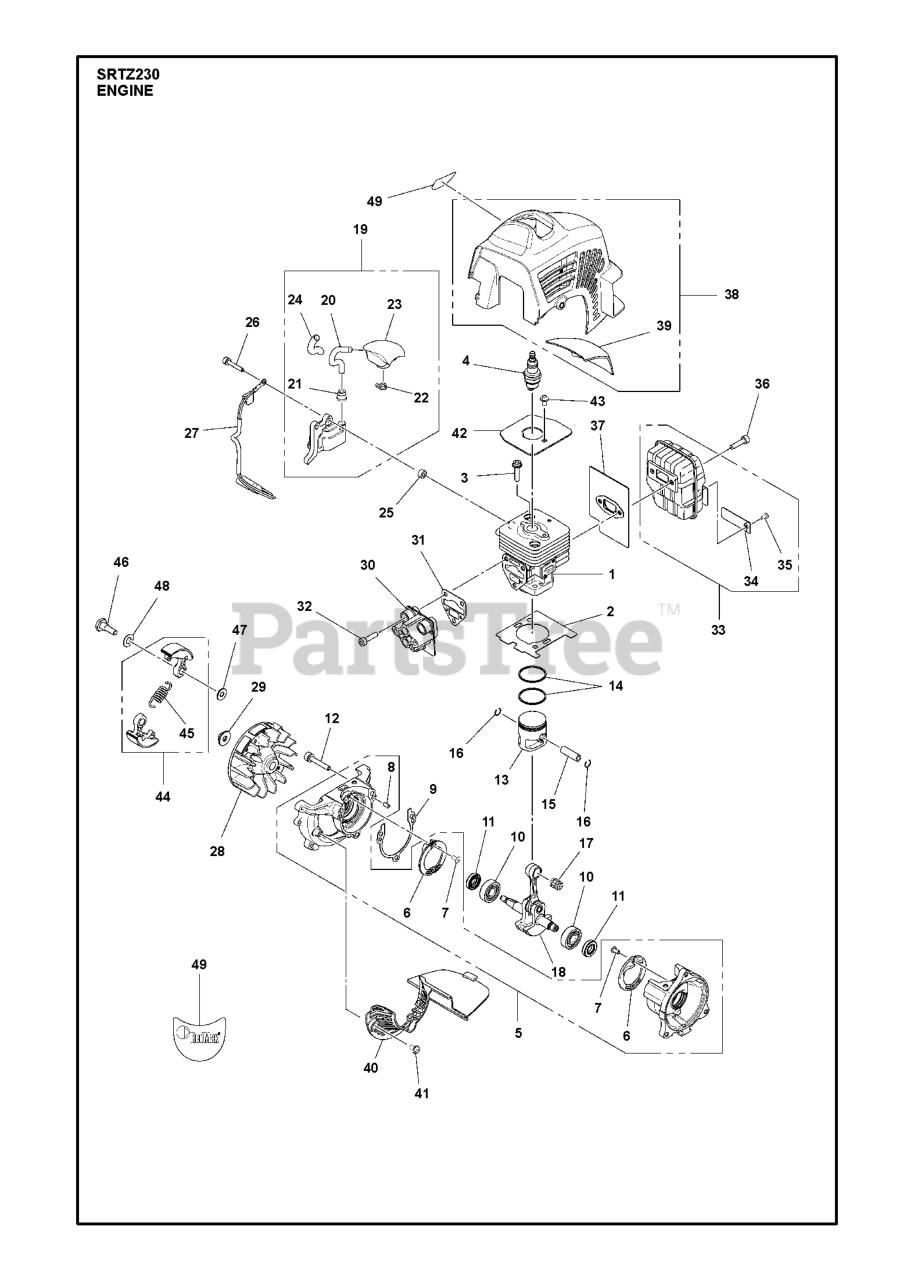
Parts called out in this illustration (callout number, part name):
1	CYLINDER COMP
2	GASKET BASE
3	BOLT
4	SPARK PLUG, BPMR8Y
6	COVER CASE
9	GASKET CASE
11	OIL SEAL 8488AA2000
14	RING PISTON
15	PIN.PISTON 8488B82600
18	CRANKSHAFT COMPLETE
19	IGNITION COIL ASSY
20	IGNITION CABLE
21	HUB CAP 848F6L71E0
23	SPARK PLUG CAP
24	TUBE (RPLS 263072210)
26	BOLT M4 X 25
27	SHORT CIRCUIT CABLE
28	FLYWHEEL
30	INSULATOR
33	MUFFLER ASSY
34	SPARK ARRESTER
35	SCREW CRPANT TYPE F ST4.2X9.5
37	GASKET MUFFLER
38	CYLINDER COVER COMPLETE
39	SHEET HEAT INSULATION TRZ230/B
40	GUARD COOLING AIR INTAKE
42	PLATE CYLINDER
44	CLUTCH ASSY
45	CLUTCH SPRING
49	DECAL BRAND
